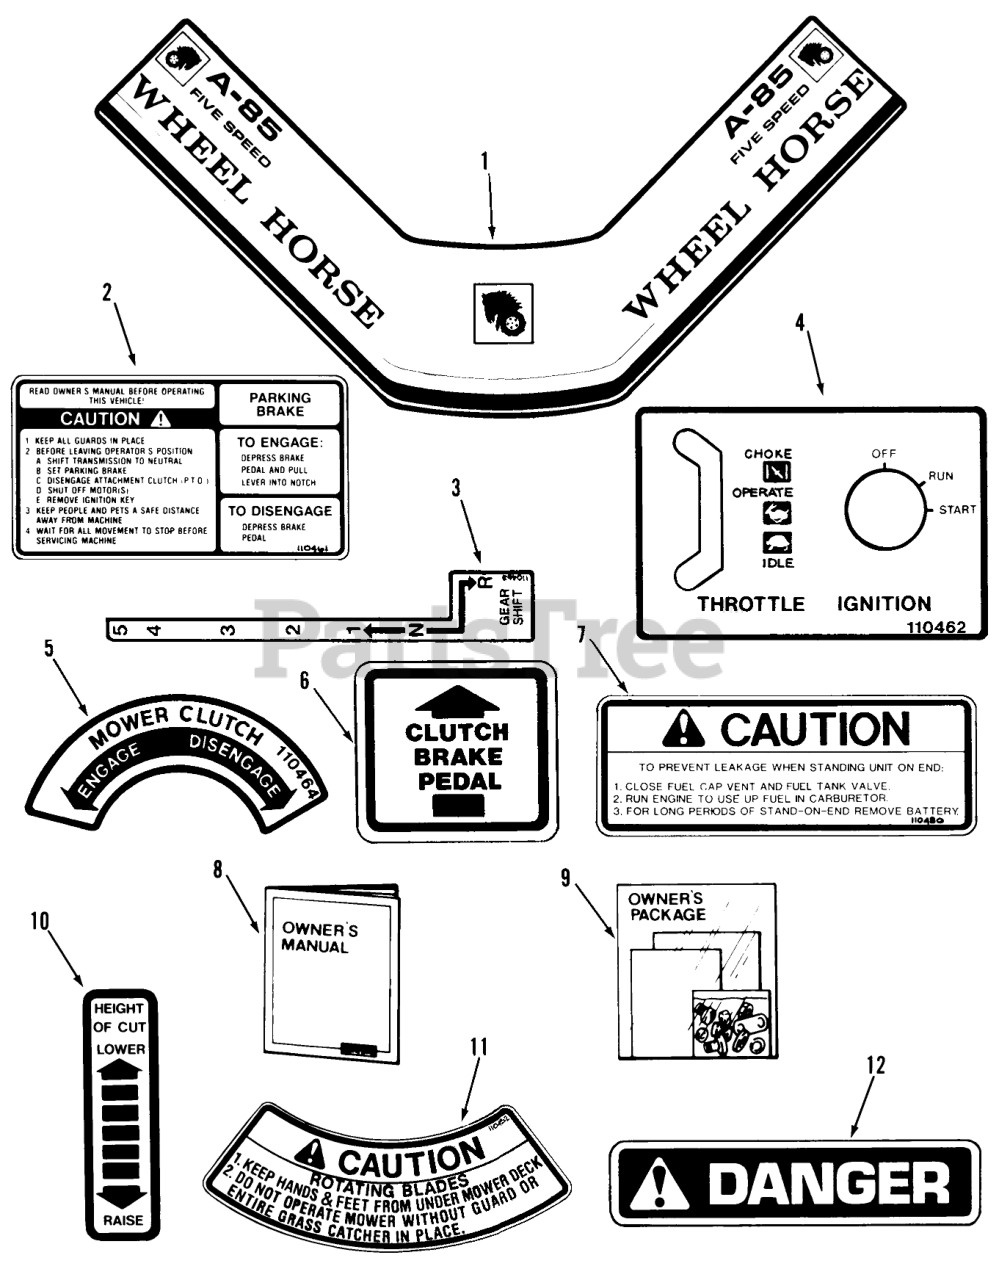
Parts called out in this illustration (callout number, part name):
1	Front Steering Shroud Decal A-115 ONLY
1	Front Steering Shroud Decal A-85 ONLY
2	Cation Parking Brake Decal
3	Shift Decal
4	Ignition Throttle Decal
5	DECAL MOWER CLUTCH
6	DECAL B&C PEDAL
7	Fuel Tank Caution Decal
8	Owners Manual
9	Loose Parts Package A-115 ONLY
9	Loose Parts Package A-85 ONLY
10	Mower Height Adjustment Decal
11	Mower Rotating Blades Decal
12	Danger Decal
